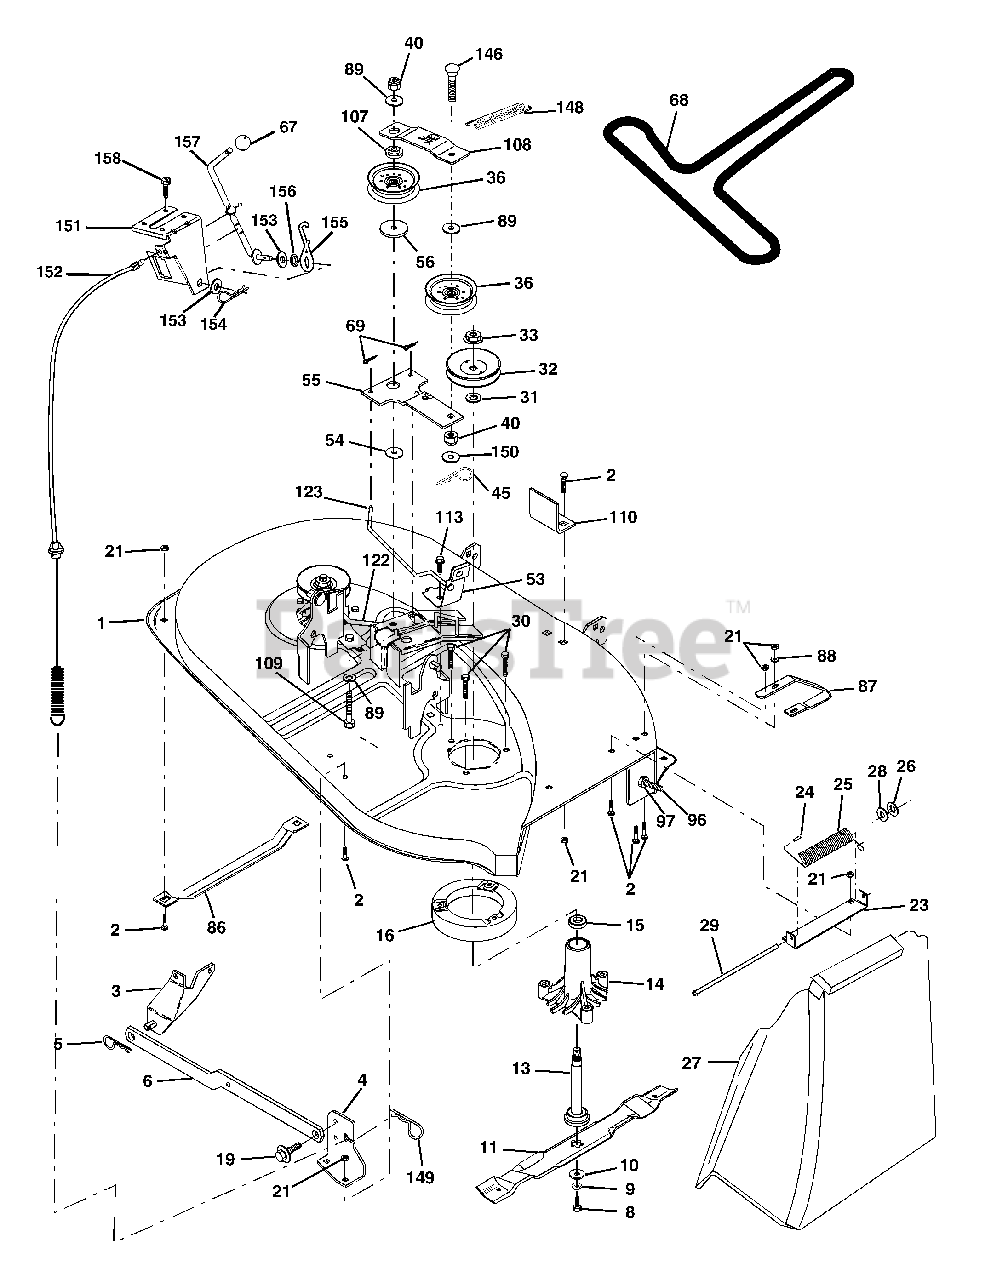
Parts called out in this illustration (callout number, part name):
1	Mower Housing Assembly
2	Bolt Carriage 5/16-18 x 3/4
3	Bracket Asm Fr. Sway Bar
4	Bracket Deck Sway Bar 38"/42"
5	Retainer Spring
6	Bar Sway Deck
8	Bolt 3/8-24 x 1.25 Grade 8
9	Washer, Lock 3/8
10	Washer, Hardened
11	Blade, 38" Mulching Std
11	Blade, 38" Mulching Premium
11	Blade, 38" Hi-LIft
13	Shaft Assembly, Mandrel, Vented
14	Housing, Mandrel, Vented
15	Bearing, Ball, Mandrel
16	Stripper, Vented Mower Deck
19	Bolt, Shoulder
21	Nut
23	Bracket, Mower Deflector
24	Cap, Sleeve
25	Spring, Torsion, Deflector
26	Nut, Push
27	Shield, Deflector
28	Washer 11/32 x 5/8 x 16 Gauge
29	Rod, Hinge
30	Screw Thdrol.
31	Washer, Spacer
32	Pulley, Mandrel
33	Nut, Toplock
36	Pulley, Idler, Flat
40	Nut, Crownlock 3/8-16 Unc
45	Retainer
53	Brake Assembly
54	Washer, Hardened
55	Idler Arm Assembly
56	Spacer, Retainer
67	Knob
68	V-Belt, 42" Mower
69	Pin, Cotter 3/32 x 3/4
86	Runner, LH
87	Runner, RH
88	Washer 11/32 x 3/4 x 16 Ga
89	Washer 13/32 x 1 x 12 Ga.
96	Bolt 3/8-16 x 1-1/4 Mulcher
97	Nut Centerlock 3/8-16 Unc
107	Spacer Retainer
108	Stiffener, Idler Arm
109	Bolt, Hex Hd 3/8-16 x 2-1/2
110	Upstop Deck Front 38"
113	Screw 5/16-1/ x 3/4
122	Rod, Brake LH
123	Rod, Brake RH
146	Bolt Carriage Idler
148	Spring Return Idler
149	Retainer Spring Yellow
150	Washer 9/32 x 3/4 x 16 Ga.
151	Bracket Clutch Cable
152	Clutch Cable 38"/46"
153	Washer Flat 3/8" Type B
154	Spring Retainer
155	Spring Retention LVR CLTCH CAB
156	Spacer Clutch Cable
157	Rod Clutch Cable 3/8"
158	Screw Hex Thd Cut 1/4-20 x 1/2
